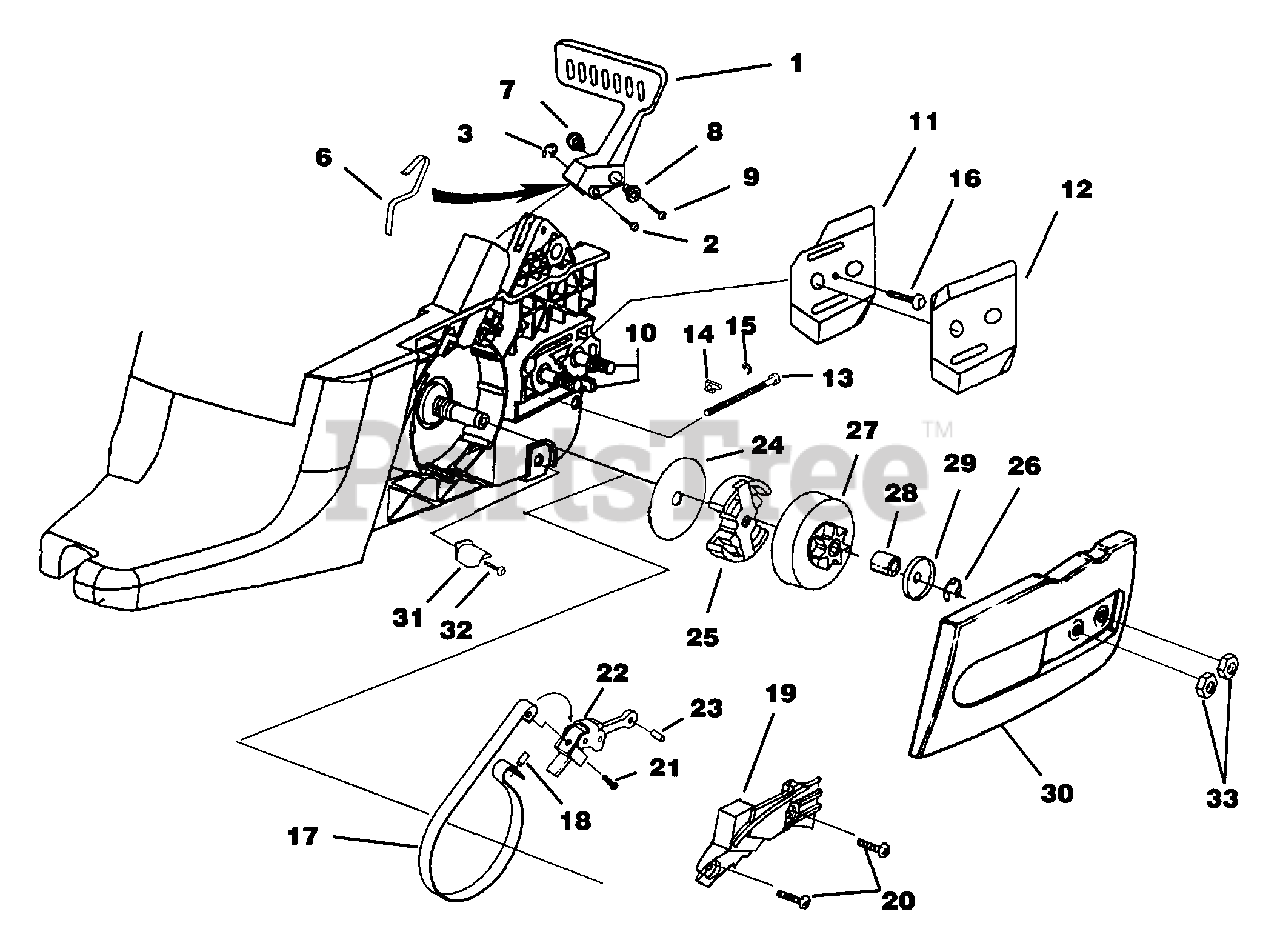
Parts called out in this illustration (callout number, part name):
1	Hand Guard Kit
2	Hand Guard Actuating Pin
3	Retaining Ring
6	Spring, Handguard
7	Pivot, L.H.
8	Pivot, R.H.
9	Screw, Hex Socket Hd. (8-32 x 5/8")
10	Guide Bar Bolt
11	Plate, Guide Bar
12	Plate, Guide Bar
13	Screw, Guide Bar Adjusting
14	Pin, Guide Bar Adjusting
15	Ring, Retaining
16	Screw, Thread Form (6-19 x 1/2")
17	Chain Brake Kit
18	Pin, Roll
19	Cover, Chain Brake
20	Screw, Pan Hd (6-19 x 1/2")
21	Screw, Pan Hd. (8-16 x .320)
22	Chain Brake Link
23	Pin, Roll
24	Thrust Washer
25	Clutch & Hardware
26	Ring, Retaining
27	Sprocket, Drum & Hardware
28	Bearing, Needle
29	Washer, Cupped
30	Drive Case Cover
31	Stop, Chain
32	Screw, Thread Form (10-14 x 3/4")
33	Nut, Hex
